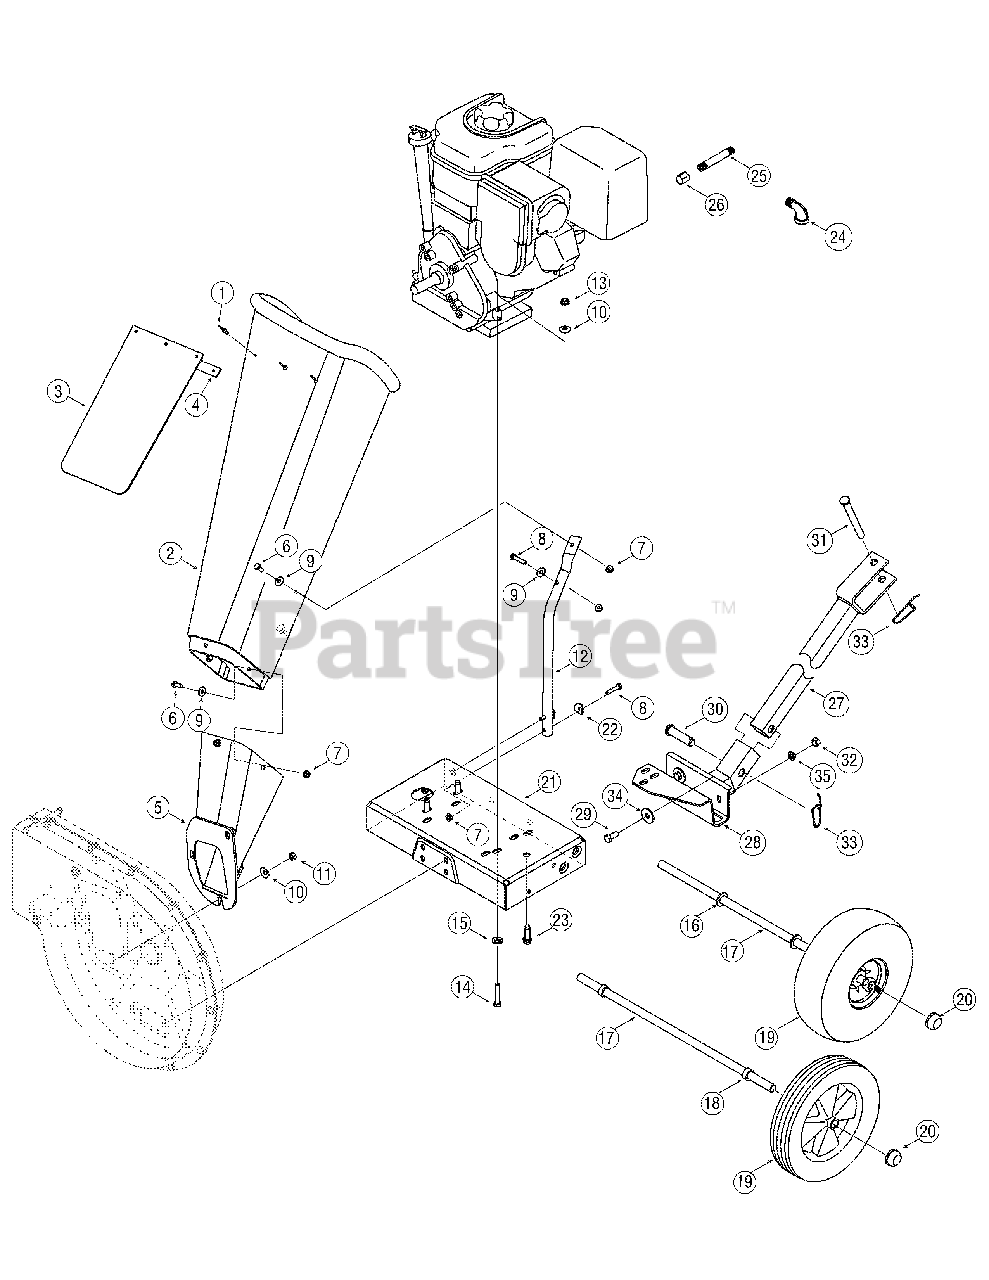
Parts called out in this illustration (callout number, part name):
1	Pop Rivet
2	Chipper Shredder Chute
3	Chute Flap
4	Chute Flap Strip
7	Hex Lock Nut 1/4-20
8	Hex Cap Screw 1/4-20 x 1.25
9	Flat Washer.28 ID x.74 OD
10	Bell Washer.340 ID x.872 OD
11	Hex Nut 5/16-18
13	Hex Lock Nut 5/16-18
14	Hex Cap Screw 5/16-18 x 1.50
14	Hex Cap Screw 5/16-18 x 1.75
15	Bell Washer 5/16 x 1.0
16	Flat Washer
17	Axle Assembly
18	Spacer
19	Wheel Comp., 10.0 x 2.5 Plastic
19	Wheel Complete, 10.0 x 4.0 Gray
20	Push Cap
22	Washer,.320 ID x.93 OD
23	Screw, 3/8-16 x 1.250
24	Elbow Fitting
25	Oil Drain Pipe
26	Oil Drain End Cap
29	Hex Cap Screw, 3/8-16 x.88
30	Clevis Pin,.625 x 2.4
31	Clevis Pin,.50 x 4.62
32	Flange Lock Nut, 3/8-16
33	Spring Pin
34	Flat Washer,.411 x 1.25 x 1.0
35	Lock Washer, 3/8
